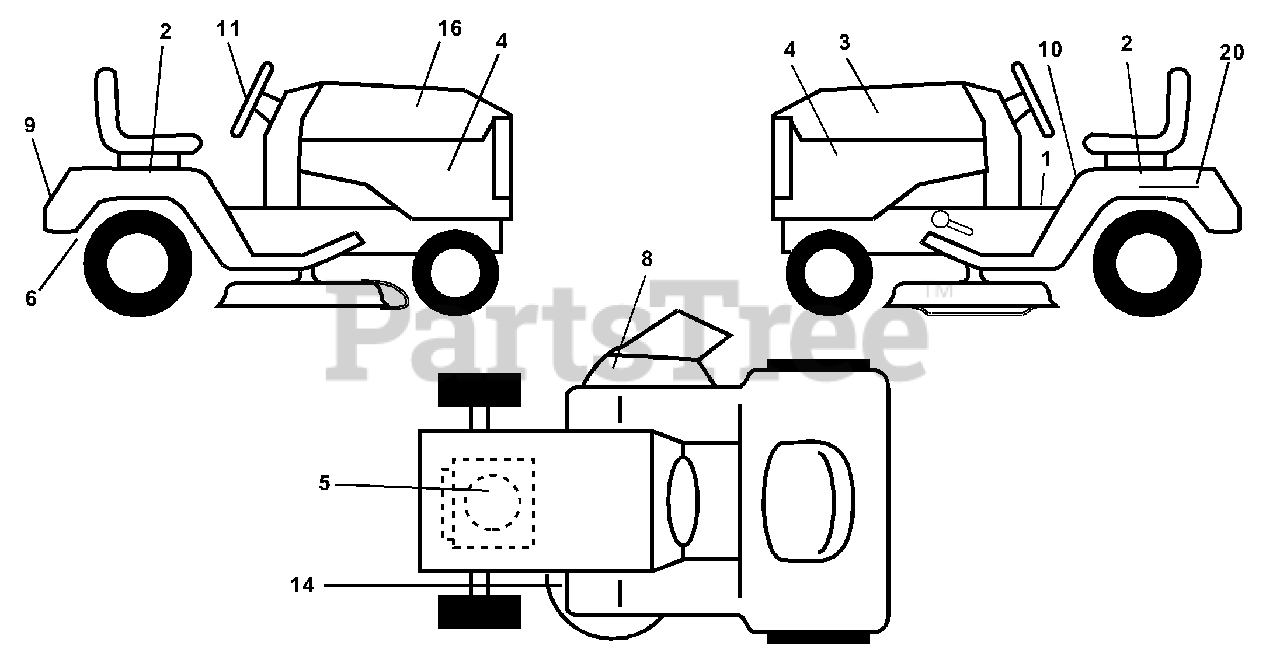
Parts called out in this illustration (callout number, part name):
1	Decal Oper
2	Decal Fender Auto
3	Decal Hood LH
4	Decal Side Panel Logo
5	Decal HP Engine
6	Decal By Pass Lt Hydro
8	Decal Mower Warn Keep Hand Away
9	Decal Fender Logo
10	Decal Fender Danger E/F
11	Decal Ins Strg Whl
14	Decal V-Belt Schematic
16	Decal Hood Rh
20	Decal Bat Dan/Psn
